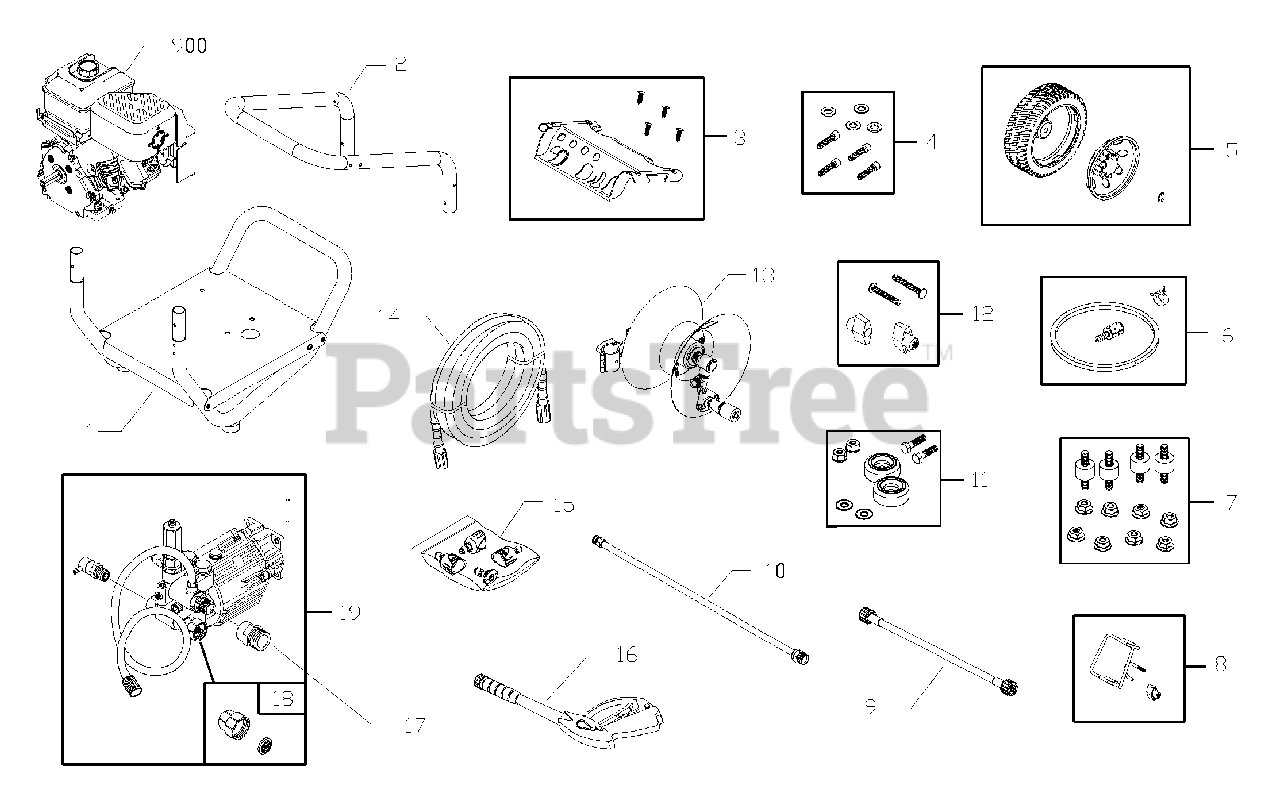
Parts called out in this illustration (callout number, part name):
3	KIT, Billboard/Decals, w/Clips
4	KIT, Pump Mounting Hardware
6	KIT, Chemical Hose & Filter
7	KIT, Engine Mounting Hardware
8	KIT, Gun Holder
10	EXTENSION, QC
11	KIT, Vibration Mount
12	KIT, Handle Fastening
13	ASSEMBLY, Hose Reel
15	KIT, Spray Tips
16	GUN
18	KIT, Inlet, Garden Hose
900	ENGINE
